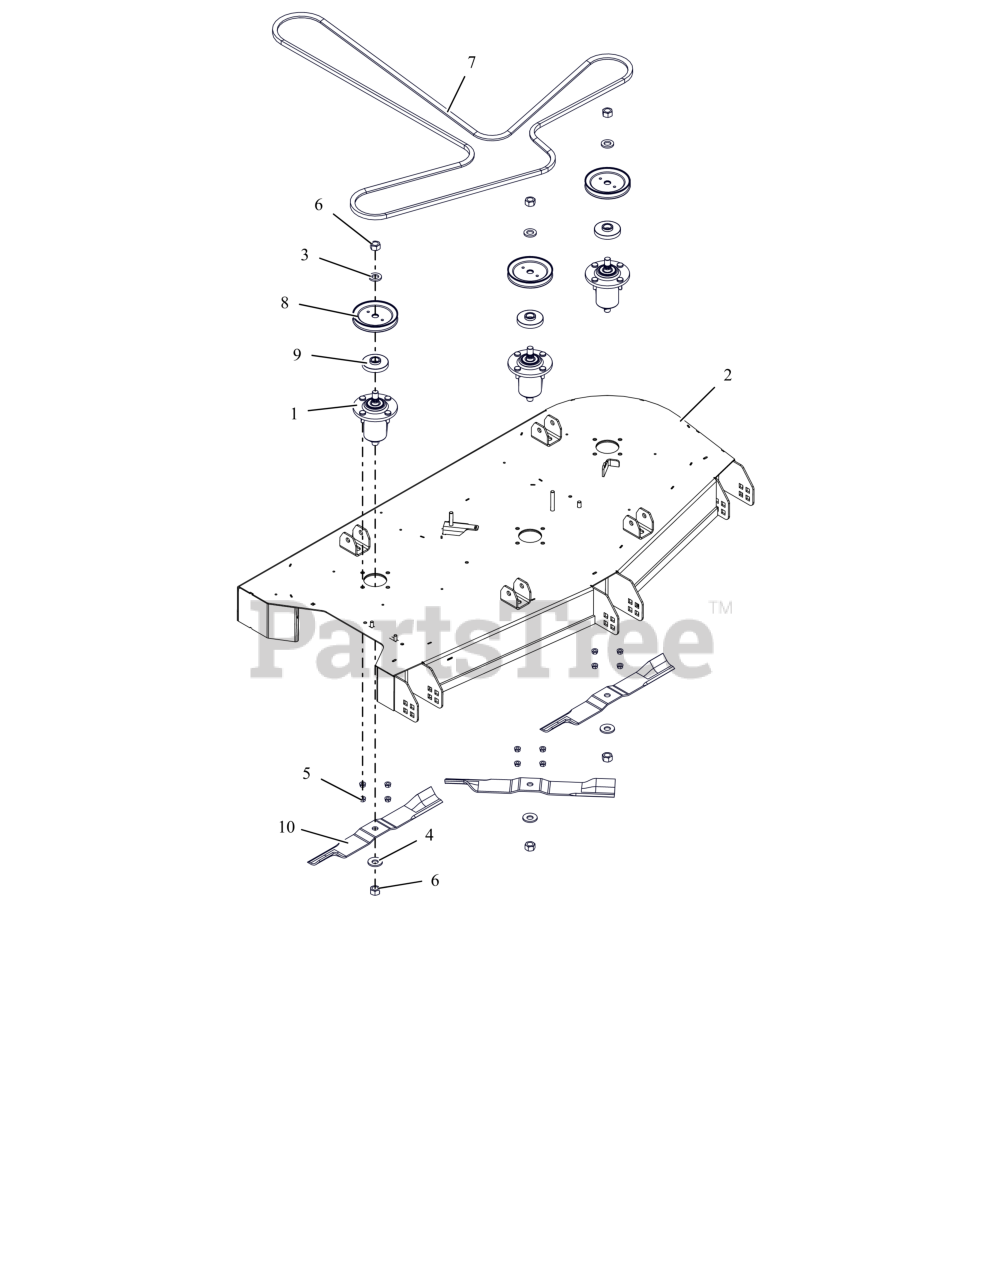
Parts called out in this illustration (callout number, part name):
1	ASM, ALUMINUM SPINDLE SUB
2	KIT,ARIENS DECK 52" WITH DECALS
4	WSHR-BLVL .669X1.535X.138
5	NUT,LK-CTR-FLG .31-18 GF ZCC
6	NUT-STD .625-18 ZCC
7	V-BELT, HA SECTION
8	PULLEY, V-4.75 ODX.625 SPLINE ID
9	SHIELD, DUST
10	BLADE, MOWER 18.0"
